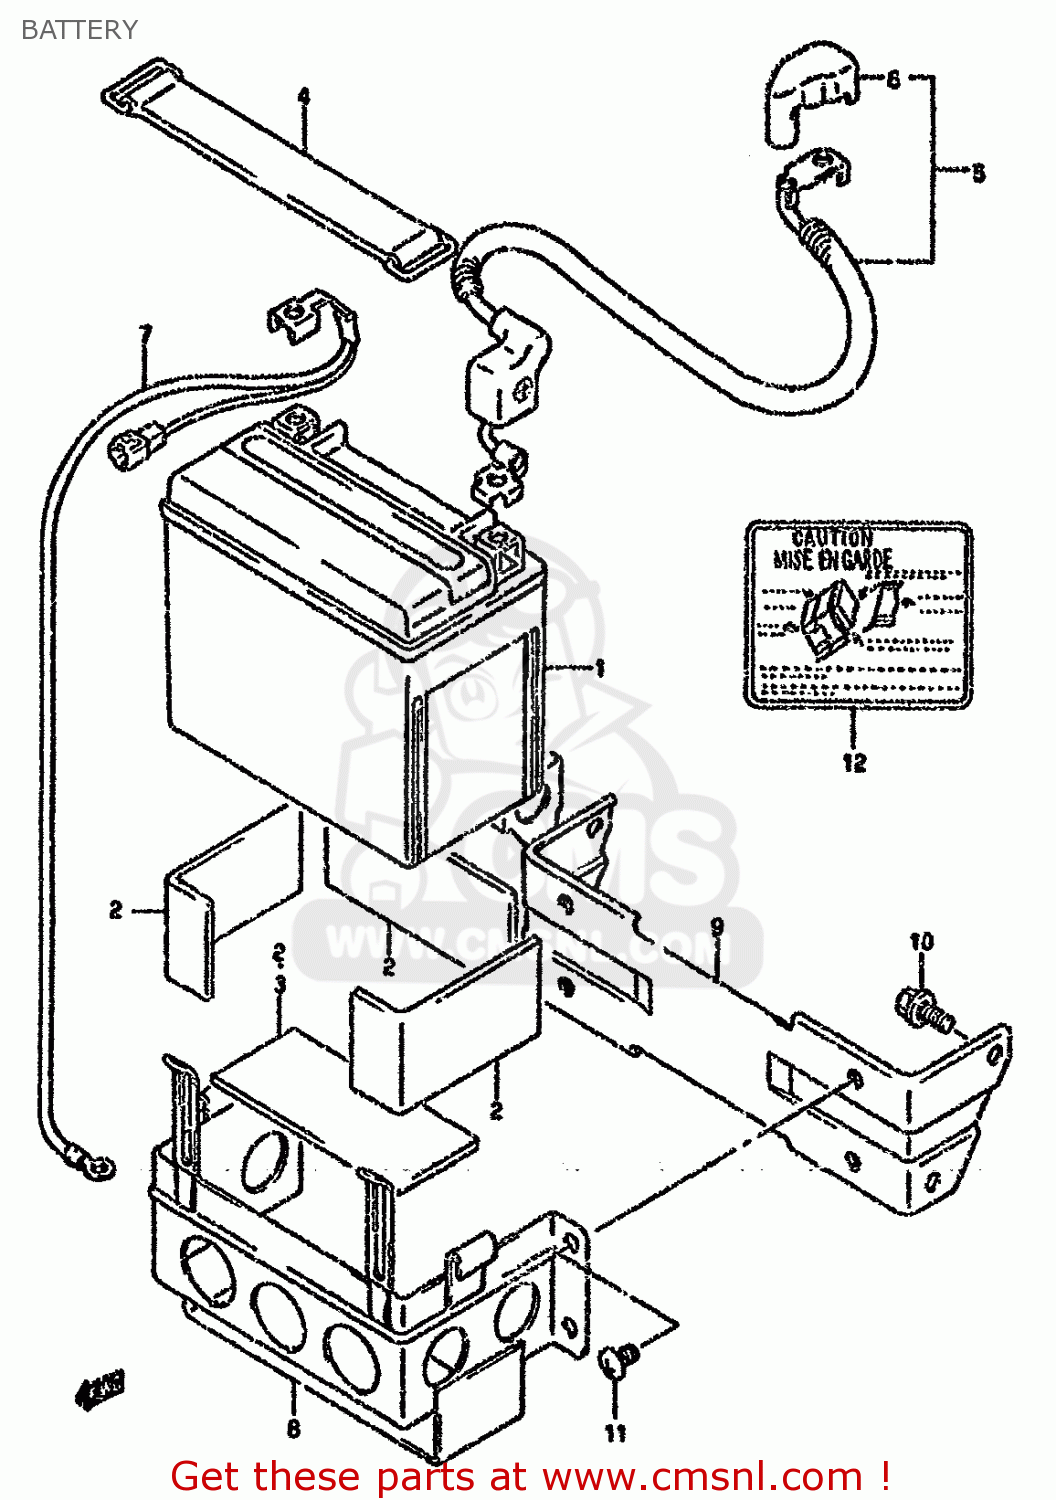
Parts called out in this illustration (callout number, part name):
1	BATTERY (YTX12-BS,12V,10AH)
2	PROTECTOR(170X95X3.0)
3	PROTECTOR,BATTERY
4	BAND
5	WIRE,BATTERY PLUS
6	CAP,BATTERY PLUS
7	WIRE,BATTERY MINUS
8	HOLDER,BATTERY
9	BRACKET,BATTERY HOLDER
10	BOLT
11	SCREW 6X12
12	PLATE,BATTERY CAUTION
